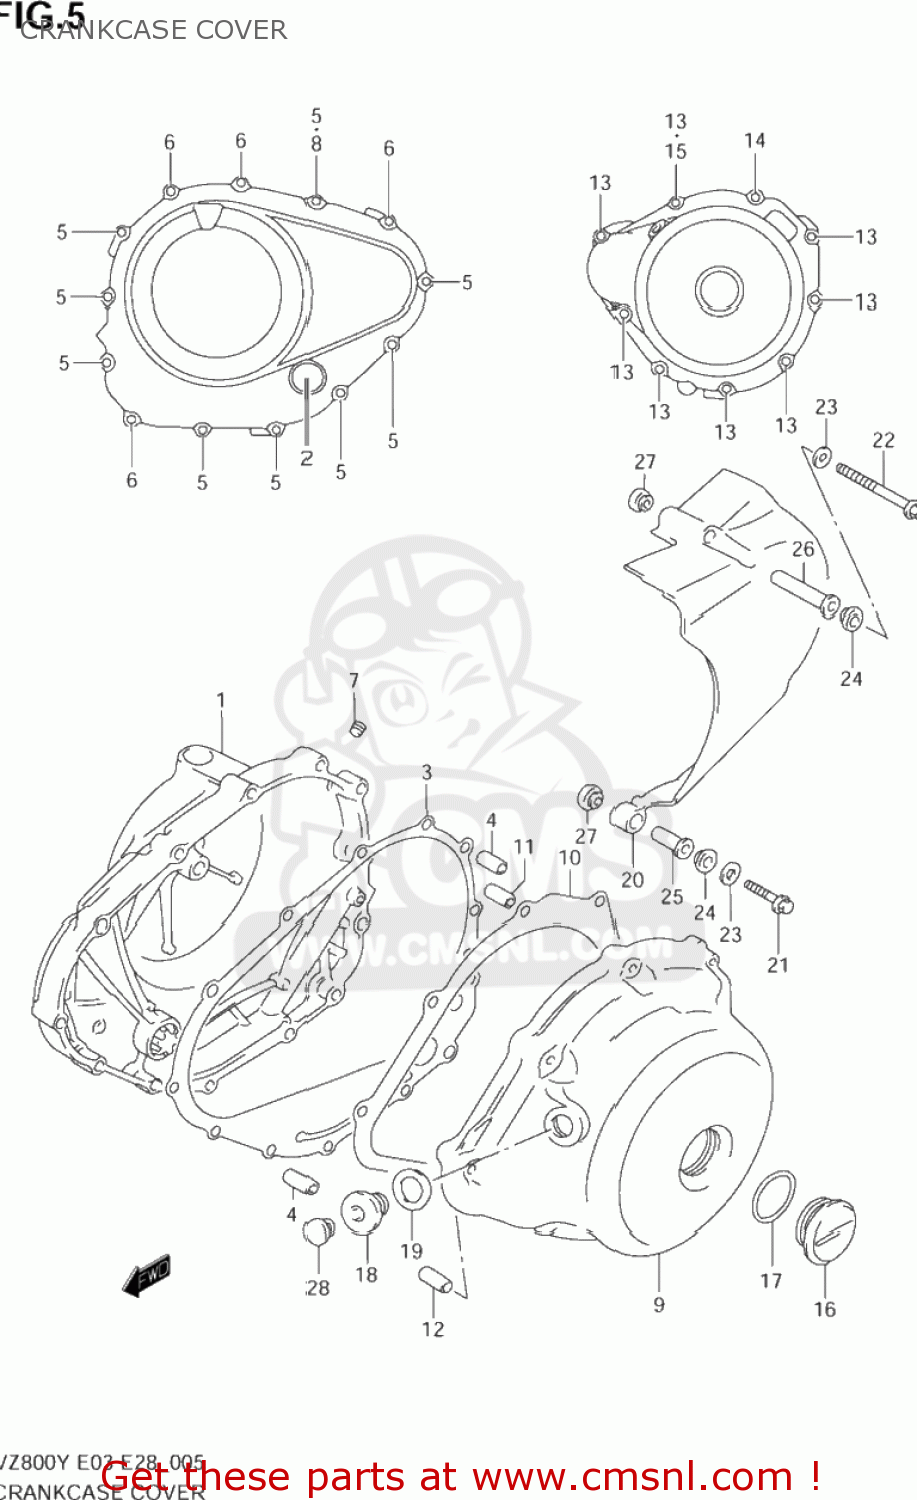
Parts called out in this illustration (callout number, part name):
1	COVER,CLUTCH
2	LENS,OIL LEVEL CHECK
3	GASKET,CLUTCH COVER
4	PIN
5	BOLT
6	BOLT
7	PLUG(1/8PT,H:5.5)
8	GASKET(5.8X11X1.2) (NAS)
9	COVER,MAGNETO
10	GASKET,CLUTCH COVER
11	PIN(8.4X11X20)
12	PIN
13	BOLT
14	BOLT
15	GASKET(5.8X11X1.2) (NAS)
16	Chrome Crankshaft Plug
17	O RING(D:3.1,ID:32.7)
18	PLUG,14X12
19	GASKET(13.8X18.8X4.8) (NAS)
20	COVER,ENGINE SPROCKET
21	BOLT
22	BOLT
23	WASHER
24	WASHER(8.7X15X2.1)
25	SPACER(6.5X9X19.4)
26	SPACER(6.5X9X47.1)
27	WASHER(8.7X16X5)
28	CAP(OD:12)
